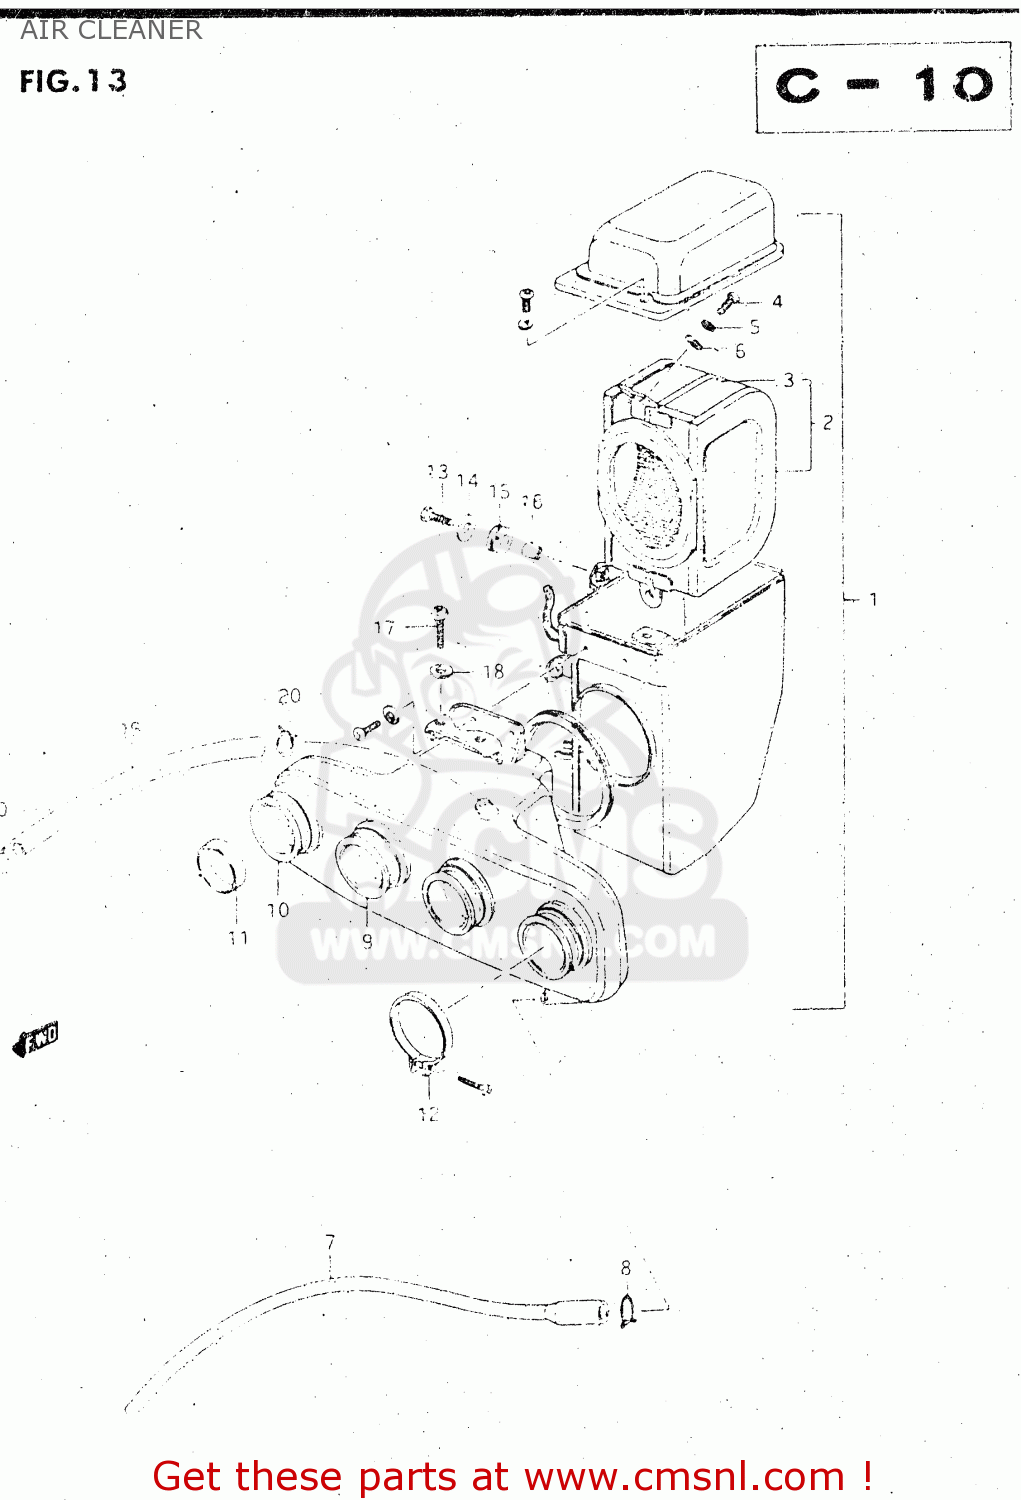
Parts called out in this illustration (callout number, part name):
1	CLEANER ASSY, AIR
2	FILTER ASSY
3	FILTER
4	SCREW
5	LOCK WASHER
6	WASHER
7	DRAIN TUBE
8	CLIP
9	TUBE,OUTLET,INNER
10	TUBE,AIR CLEANER OUTLET B
11	RING,CARBURETOR AIR INLET HOSE
12	CLAMP
13	BOLT
14	WASHER
15	CUSHION
16	SPACER (6.1X9X9)
17	SCREW 6X12
18	WASHER
19	HOSE
20	CLIP
